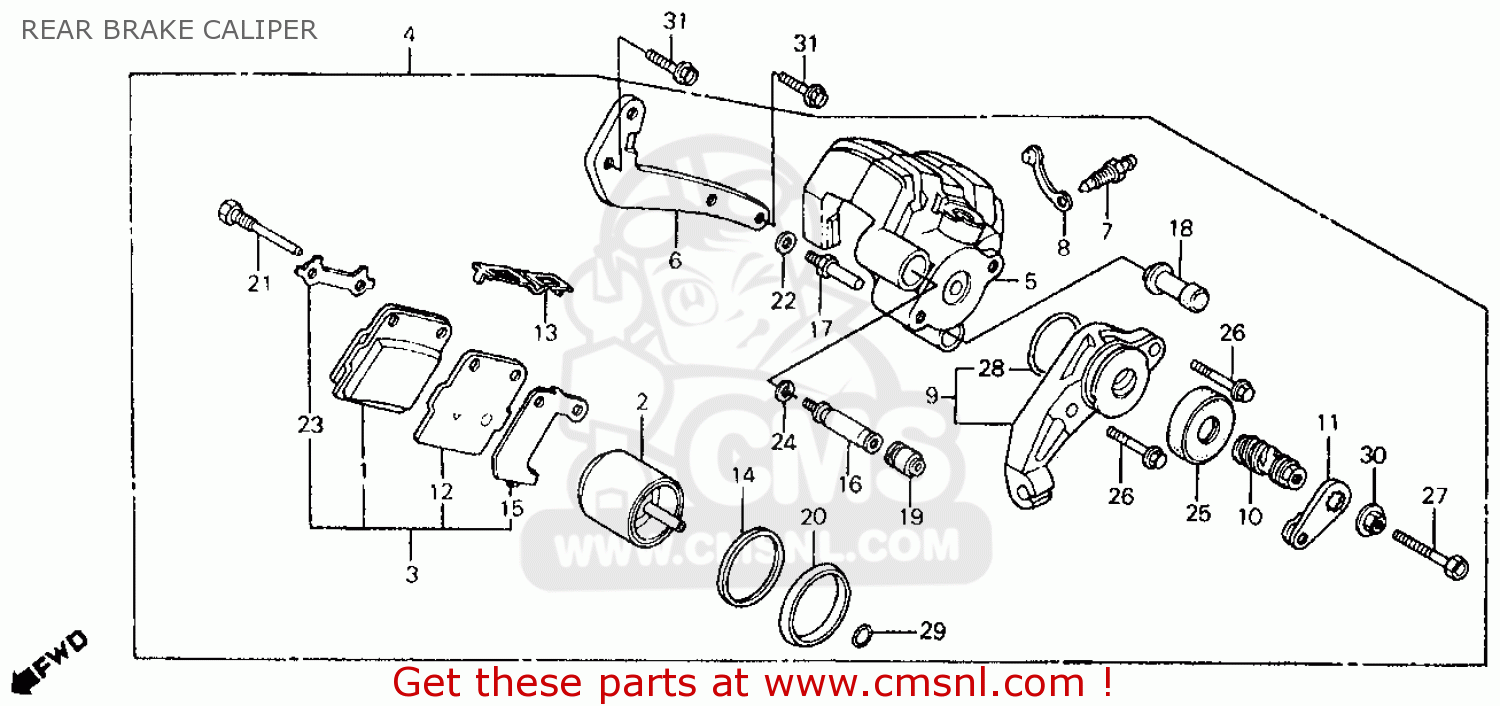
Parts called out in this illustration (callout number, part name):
1	PAD COMP.,RR. (MCA)
2	PISTON COMP
3	PAD SET,REAR (MCA)
4	CALIPER ASSY.,RR.
5	CALIPER COMP.,RR.
6	BRACKET,RR.
7	SCREW, BLEEDER
8	CAP,BLEEDER
9	PARKING BRAKE
10	SHAFT R.
11	ARM
12	PAD COMP. (MCA)
13	SPRING,PAD
14	DUST SEAL
15	SHIM,L.
16	PIN,SLIDE
17	PIN,BOLT
18	BUSH,PIN
19	BOOT,PIN
20	SEAL,PISTON
21	PIN,HANGER
22	WASHER,WAVE
23	WASHER,TONGUED
24	WASH,CONICAL SPG
25	BOOT,MASTER CYLIN
26	BOLT,8X25
27	BOLT,8X40
28	O-RING,31.2X1.9
29	O-RING,7.8X1.9
30	NUT-WASH.,8MM
31	BOLT,FLANGE,8X14
